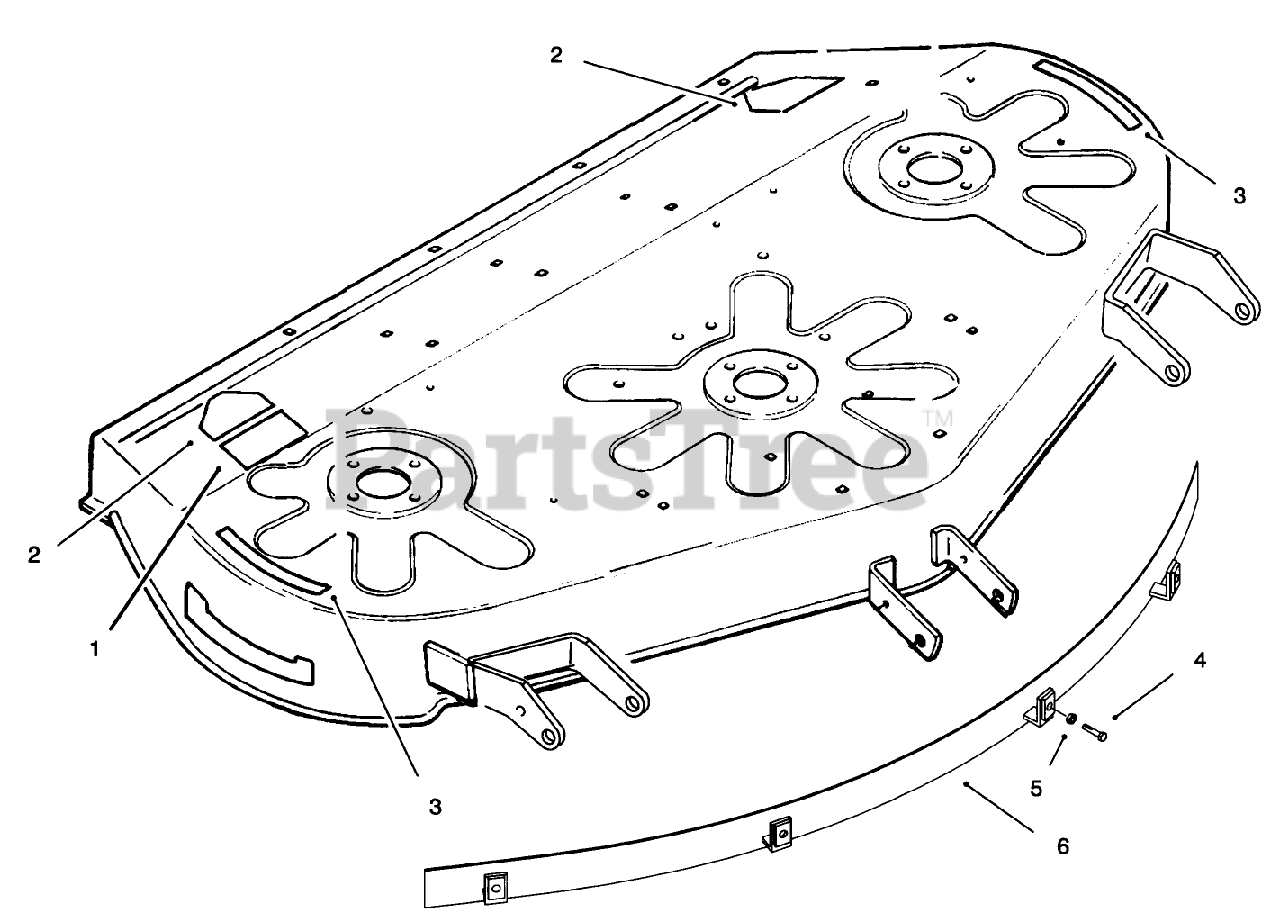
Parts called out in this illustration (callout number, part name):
1	Decal-Height & Belt
2	DECAL-DANGER
3	DECAL - DANGER
4	Screw-Hex Hd.
5	NUT-JAM
6	Front Shield-42"
